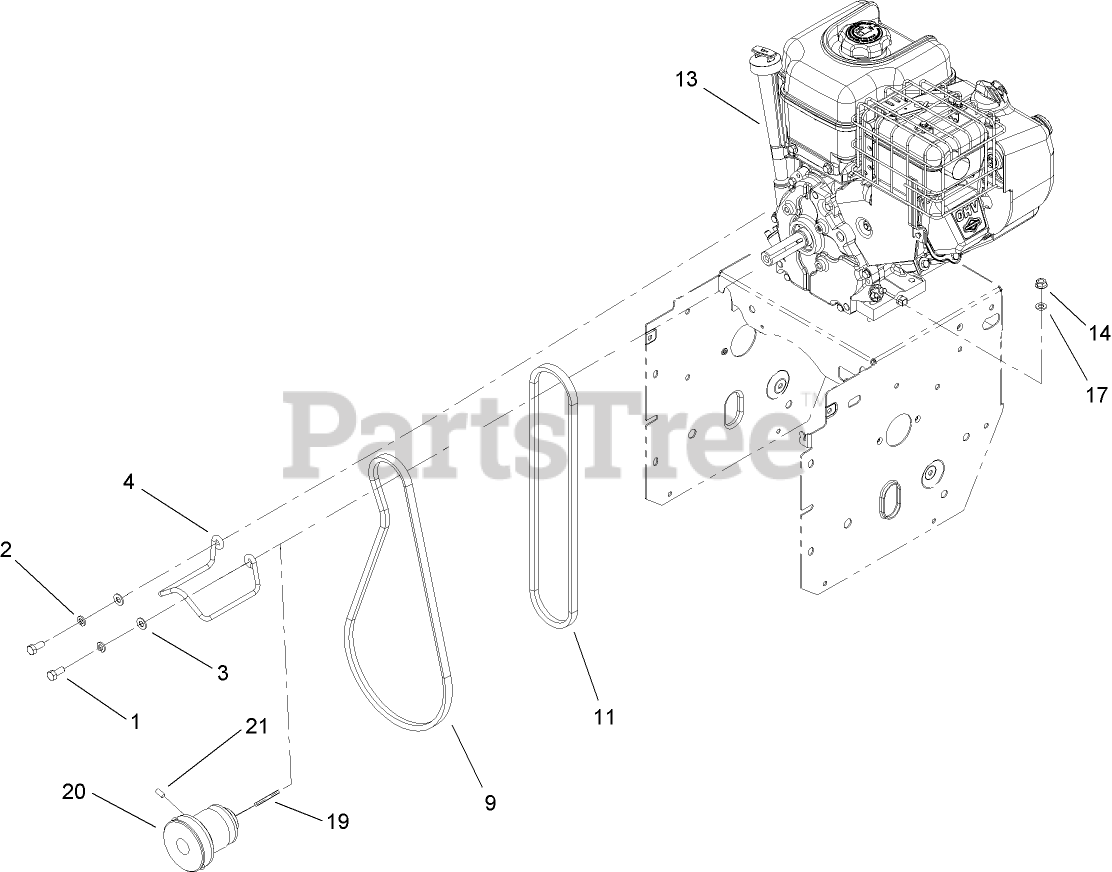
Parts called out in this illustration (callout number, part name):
1	SCREW-HH
2	WASHER-LOCK
3	WASHER-PLAIN
9	BELT-V
11	V BELT-TRACTION
13	Loose Parts Package
14	NUT-HF
17	WASHER-FLAT
19	KEY-SQUARE
20	PULLEY-ENGINE
21	SCREW-SET, HSH
